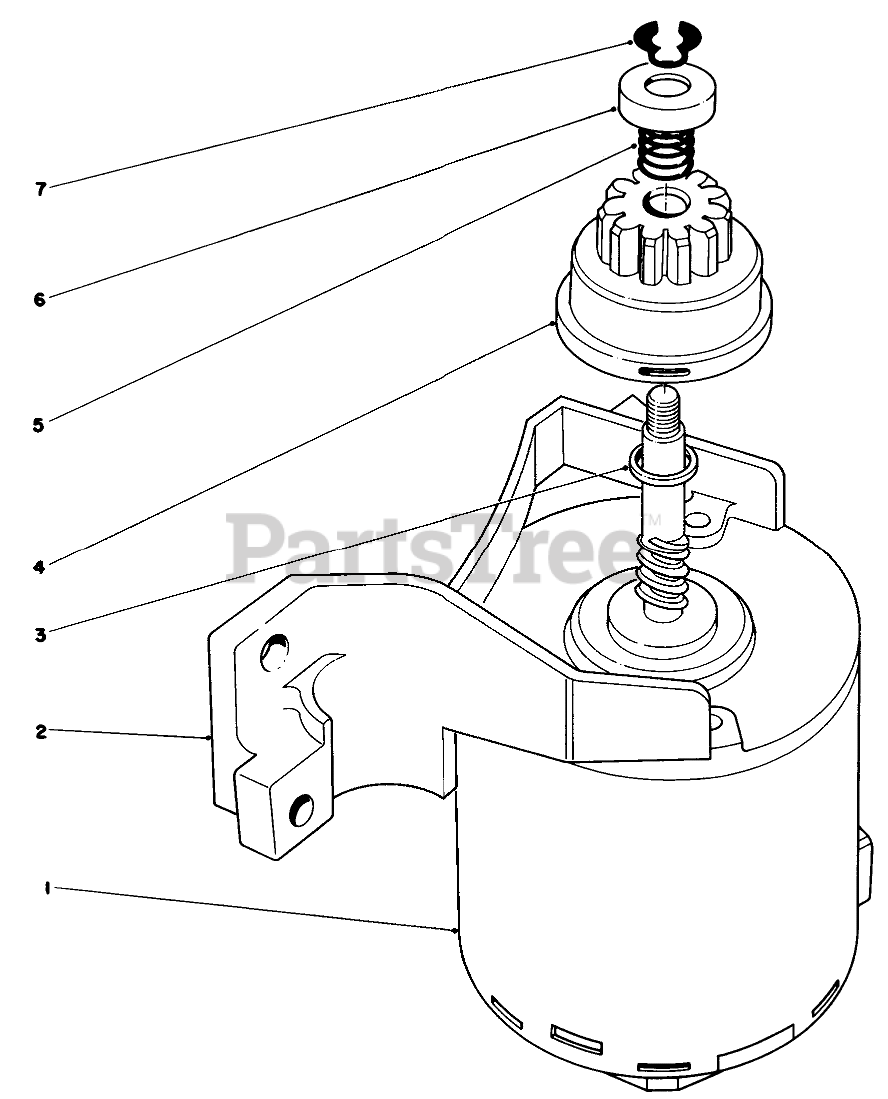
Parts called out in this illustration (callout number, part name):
1	END FRAME W/BRUSH
2	BRKT END FRAME
3	SPACER
4	PINION ASM
5	COMPRESSION SPRING
6	PINION STOP
7	RING-RETAINING
